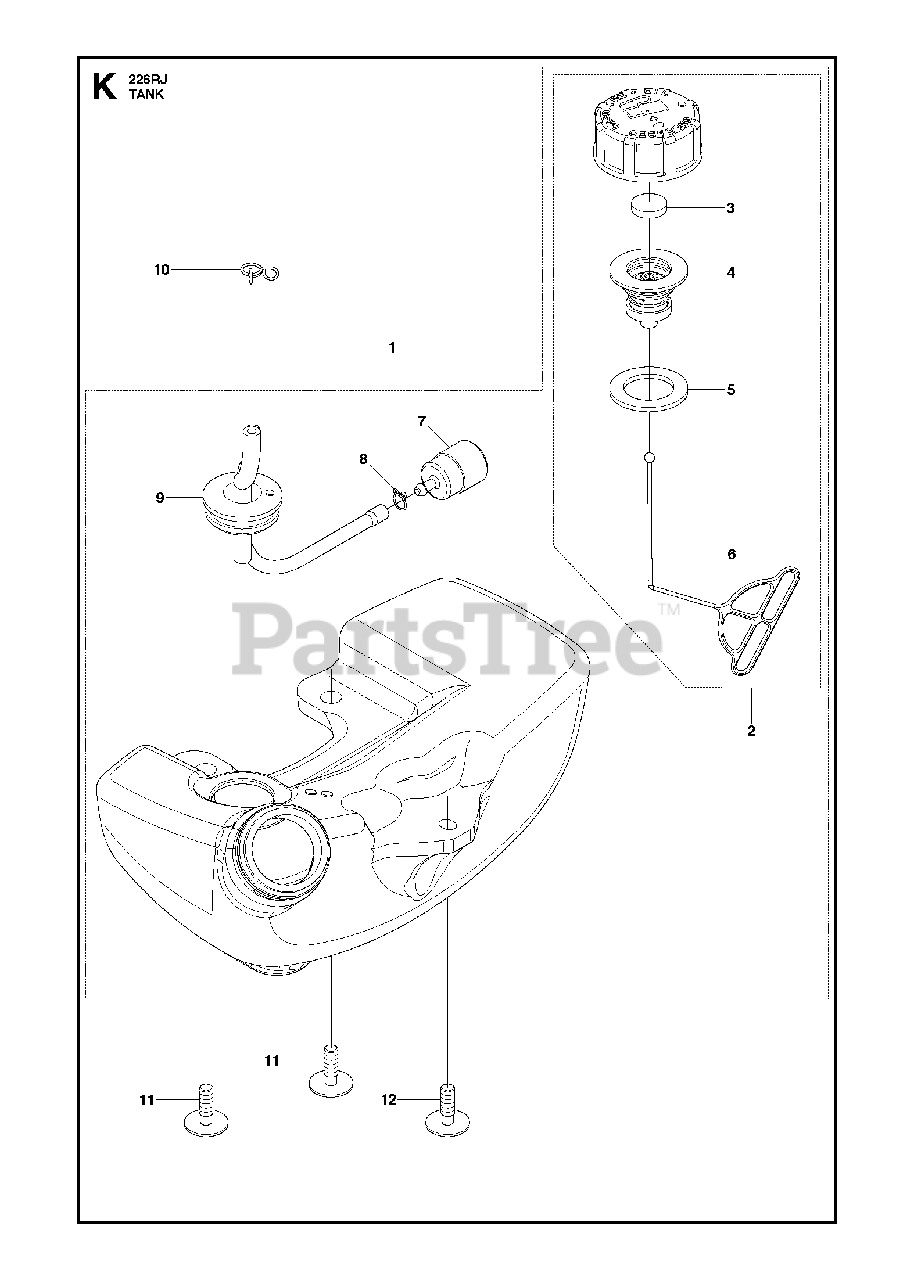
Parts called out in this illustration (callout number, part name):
2	CAP-A
3	FILTER
4	HOLDER-A
5	PACKING
6	STOPPER
7	FILTER
8	CLIP
9	PIPE COMPLETE
